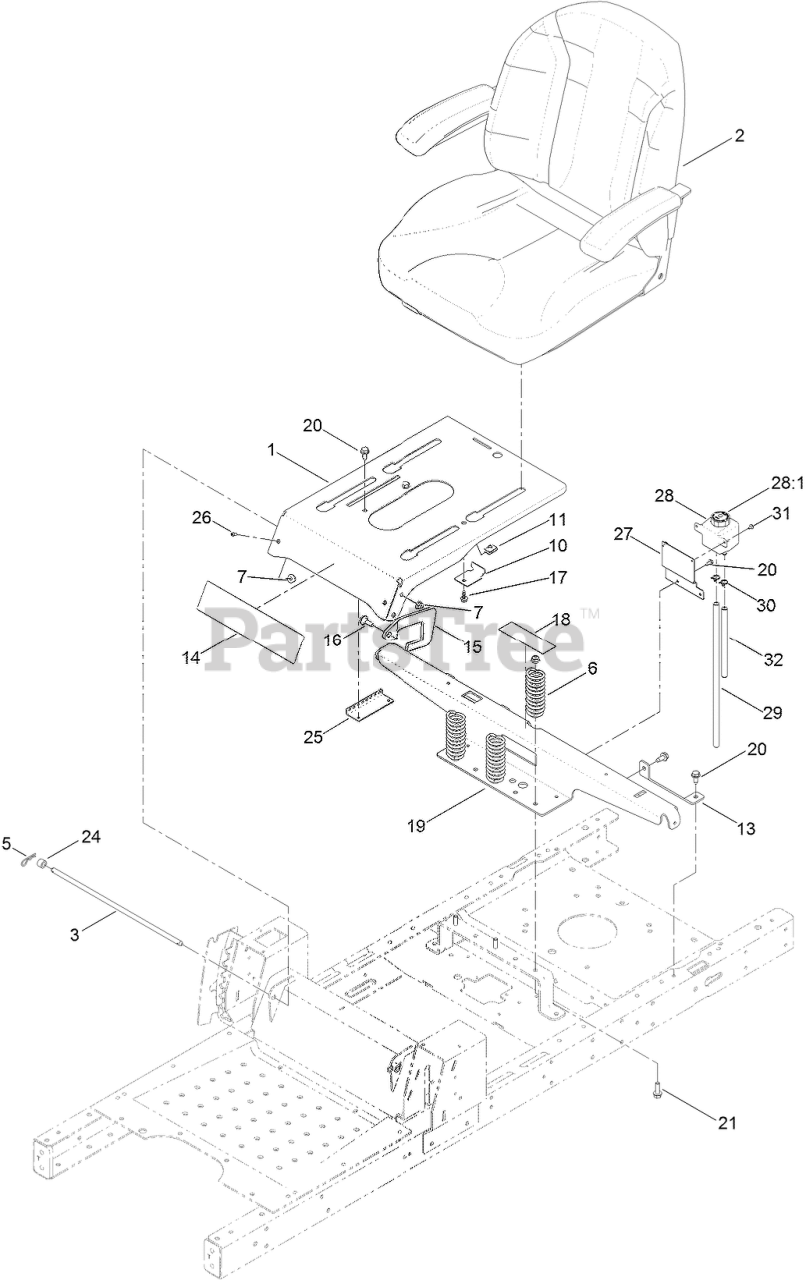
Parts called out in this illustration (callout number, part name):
1	PAN-SEAT
2	SEAT ASM
3	ROD-STOP
5	PIN-COTTER
6	SPRING-COMPRESSION
7	NUT-HF, NI
10	BRACKET-STOP, SEAT
13	SUPPORT-TANK, REAR
14	DECAL-TIMECUTTER
15	PLATE-STOP
16	SCREW-SHOULDER
17	SCREW-HHF
18	DECAL-SERVICE, CE
19	SUPPORT-POD, WIDE
20	SCREW-HWHTF
21	SCREW-HHF
24	BUSHING-LEVER, LIFT
25	BRACKET-LATCH, SEAT
26	SCREW-HSBH
27	MOUNT-TANK
28	VENT-TANK, HYD
28:1	CAP-RESERVOIR, HYD
29	HOSE-OVERFLOW
30	CLAMP-HOSE
31	SCREW-HHFTF
32	HOSE-OVERFLOW
